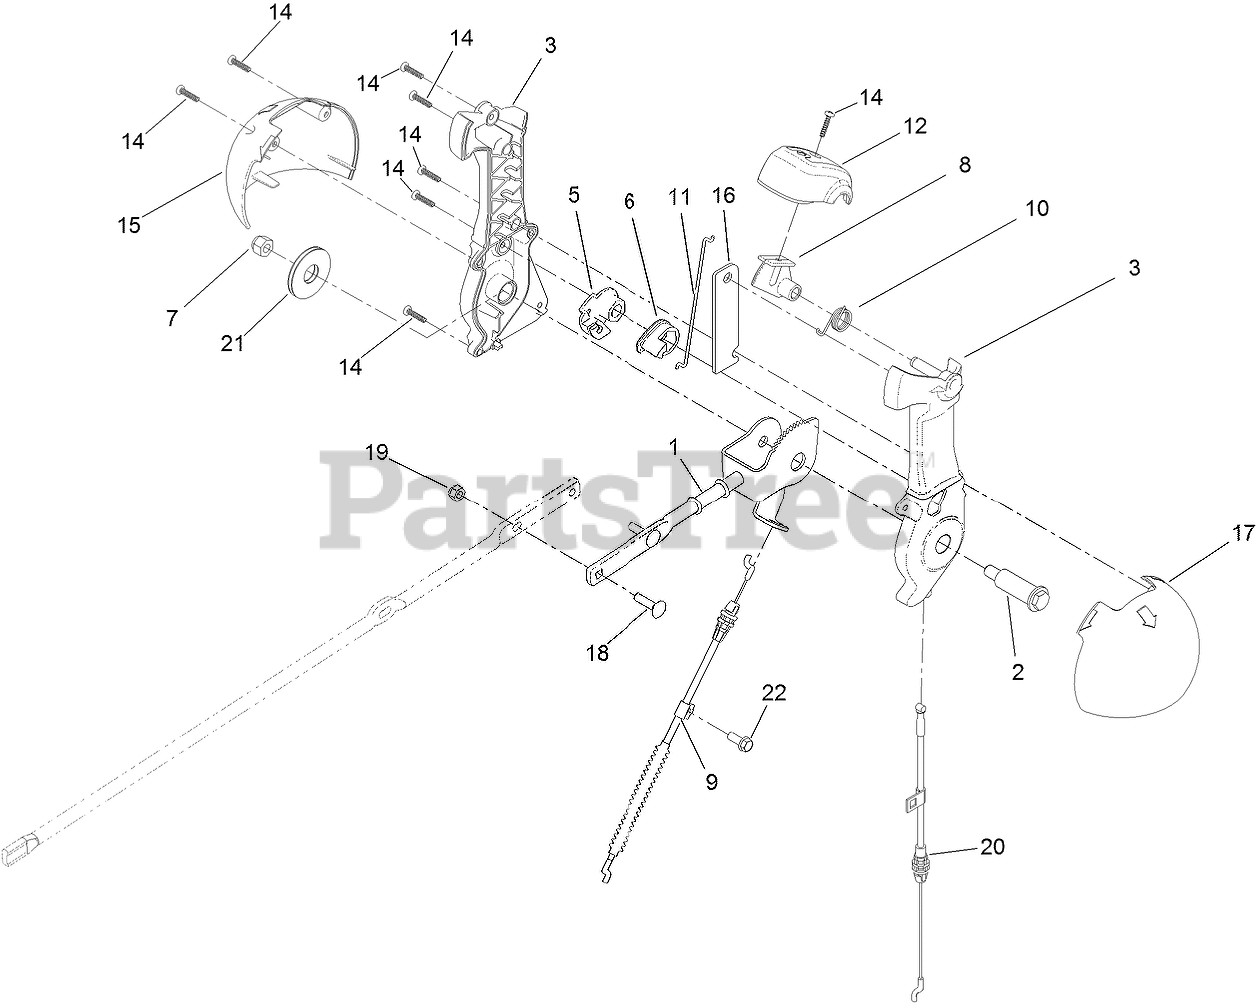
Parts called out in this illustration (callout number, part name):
1	ROD-CONTROL, CHUTE
2	SCREW-SHOULDER, HWH
3	CHUTE CONTROL LEVER ASM
5	LEVER-CABLE, DEFLECTOR
6	PAWL-LATCH
7	NUT-HEX
8	TRIGGER-LATCH
9	CABLE-CONTROL, DEFLECTOR
10	SPRING-TORSION
11	LINK-LATCH
12	CAP-LEVER
14	SCREW-PPH
15	GLOBE-QUICKSTICK, RH
16	PLATE-STIFFNER
17	GLOBE-QUICKSTICK, LH
18	BOLT-CARR
19	NUT-HEX
20	CABLE-RELEASE, CHUTE
21	WASHER-FRICTION, COMPOSITE
22	SCREW-HWH
